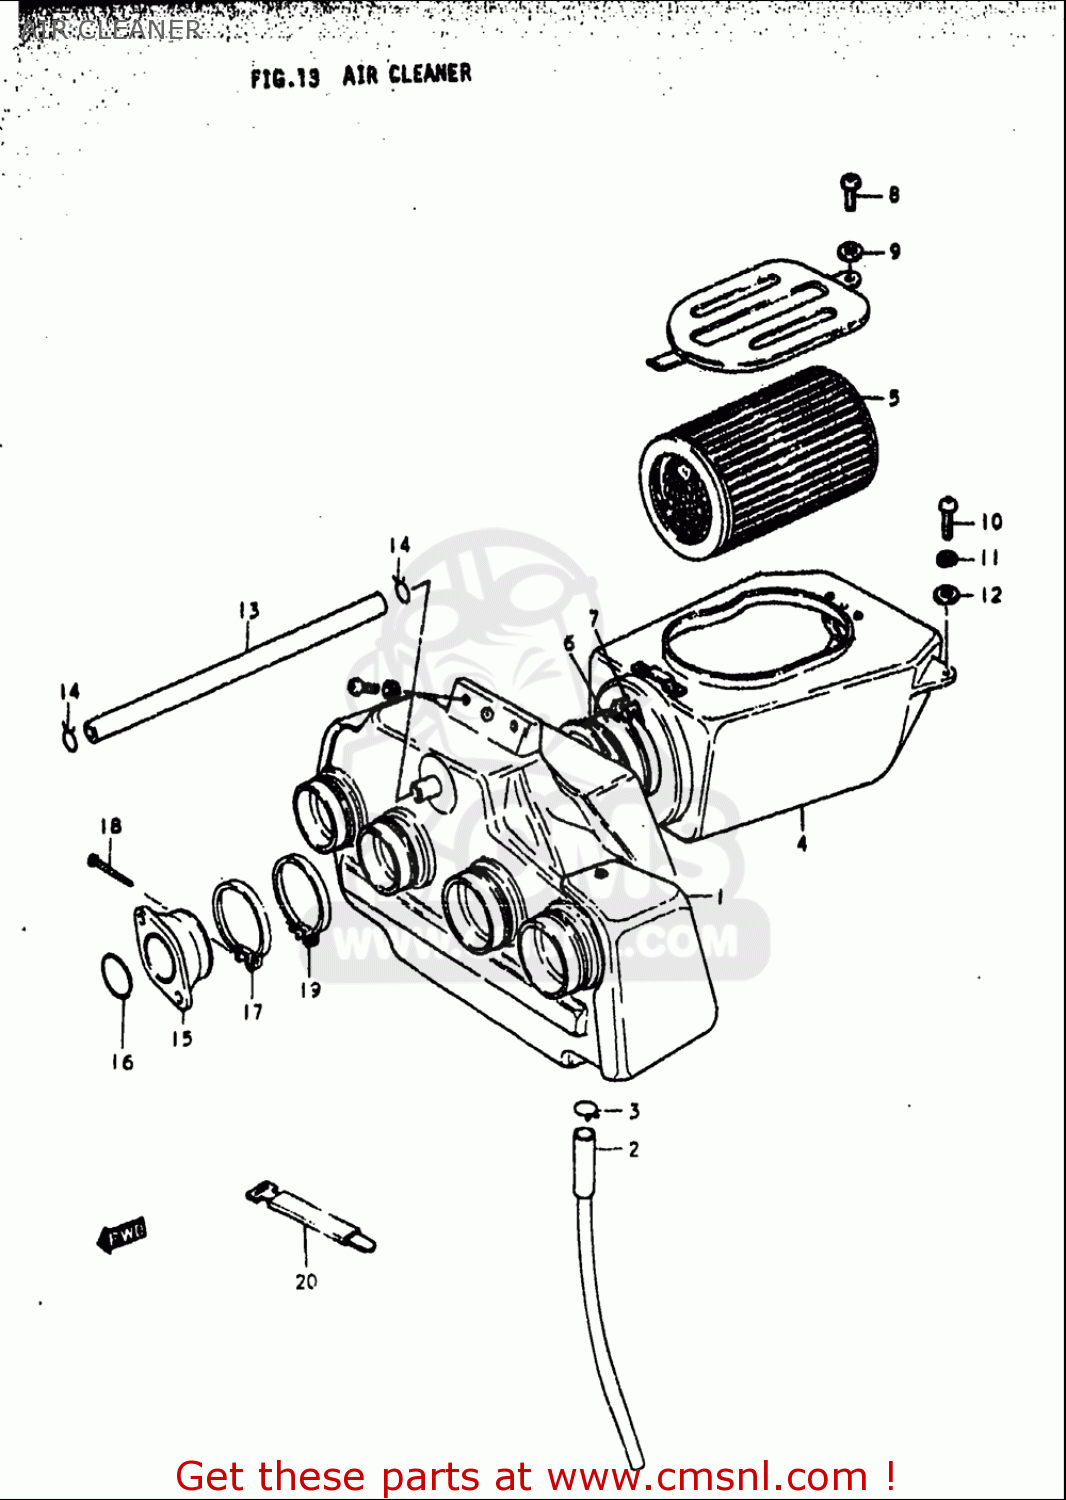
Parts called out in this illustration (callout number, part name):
2	TUBE,DRAIN
3	CLIP
4	CASE ASSEMBLY,AIR CLEANER
5	FILTER,AIR CLEANER
6	HOSE,AIR CLEANER
7	BAND
8	SCREW
9	WASHER
10	BOLT
11	WASHER,LOCK
12	WASHER
13	HOSE(11X15X2000)
14	CLIP
15	PIPE,INTAKE
16	O RING(D:2.4,ID:31.7)
17	CLAMP
18	SCREW
19	CLAMP
20	CLAMP(L:120)
